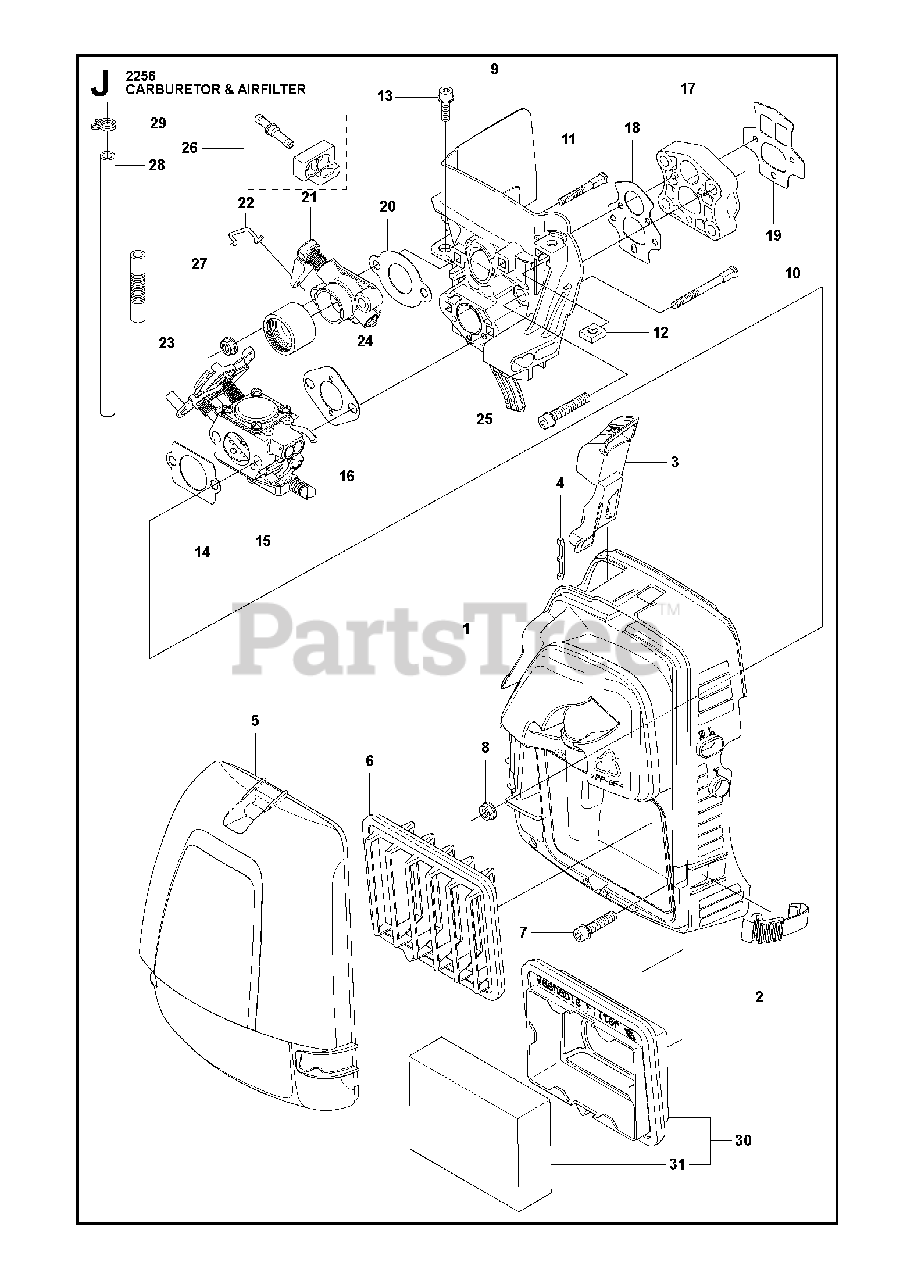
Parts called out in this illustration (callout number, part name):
3	CHOKE CONTROL
6	FILTER
9	INSULATION WALL
15	CARBURETOR
16	GASKET
17	MANIFOLD
18	GASKET
19	GASKET
21	VALVE HOUSING
24	INLET PIPE
25	SCREW IHSCFM
26	GROMMET
27	SUCTION HOSE
28	FUEL HOSE
29	HOSE CLAMP
30	FILTER
31	FILTER
